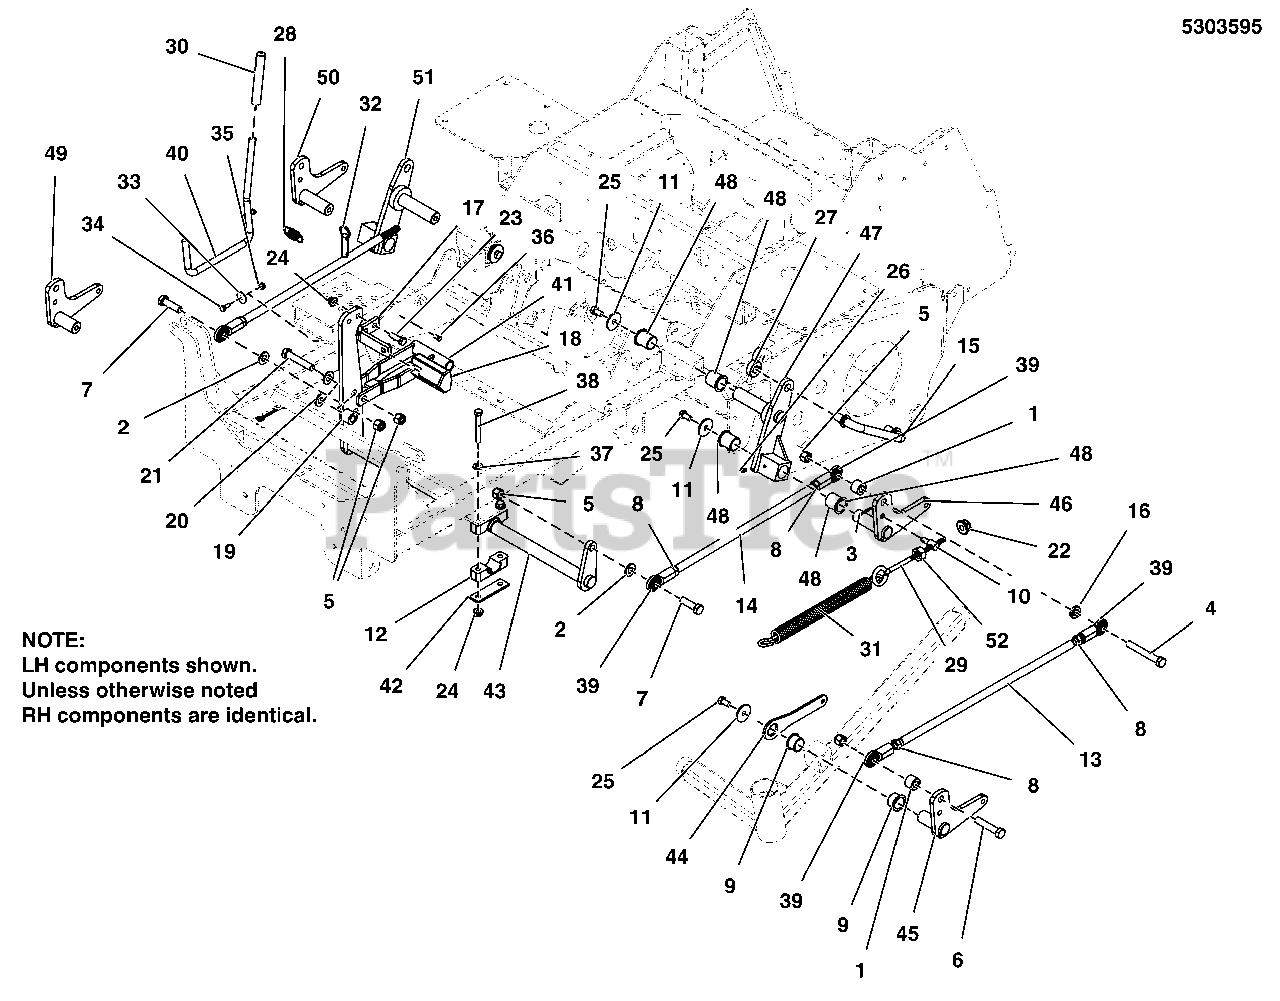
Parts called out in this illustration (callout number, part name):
1	SPACER, .52 X 1.00 X .75, CZ
2	WASHER, 1/2" GR. 9 FLAT
3	PIN, COTTER, 1/8" X 3/4
4	CAPSCREW, Hex Hd, 1/2-13 x 3-1/2
5	NUT, Hex, Nylon Lock, 1/2-13
6	BOLT, 1/2-13 X 2-1/2 GD5 YZ
7	BOLT, 1/2-13 X 1-3/4 GD5 YZ
8	NUT, Hex Jam, 1/2-20
9	BUSHING, 1.00 X 1.13 X .75, PLASTIC
10	ADJUSTER, DECK HANGER
11	WASHER, .390 X 1.50 X .109, YZ
13	ROD, 1/2-20 X 24.50
14	ROD, DECK LIFT, 19.25, CZ
15	ROD, SUSPENSION LINK, IS700, CZ
16	SPACER, .52 X 1.00 X .22, PM, CZ
17	PEDAL, FOOT - BLK
18	RUBBER, FOOT PEDAL
19	SPACER, .52 X 1.00 X .88, PM, CZ
20	WASHER, 1/2
21	BOLT, 1/2-13 X 2-3/4 GD5 YZ
22	NUT, Hex, Nylon Lock, 3/8-16
23	CAPSCREW, Hex Head, 3/8-16 x 1-1/4
24	NUT, 3/8-16, Hex Flange Nylock
25	BOLT, 3/8-16 x 3/4, GD5, YZ WITH PATCH
26	GREASE FITTING, 1/4-28 STRAIGHT
27	COLLAR, 5/8" SPLIT
28	SPRING-EXT, .740 ODX2.025LGX.072WR, BLK
29	EYEBOLT, 3/8-16 X 8, 3 THRD, 1 EYE, CZ
30	GRIP, FOAM, .475 X 4.35 X .095
31	SPRING-EXT, 1.00 ODX13.25LGX.177WR, BLK
32	PIN, HITCH, 1/2 X 2.00 OAL, YP
33	WASHER, 1/4
34	CAPSCREW, Hex Head, 1/4-20 x 5/8, GR5
35	NUT, 1/4-20, GR5 Flanged Nylock, Zinc/Clear
36	PIN, CLEVIS, 1/4 X 1/2, PLATED
37	WASHER, 3/8 (.406 X .816 X .65), Flat, Zinc/Clear
38	CAPSCREW, Hex Head, 3/8-16 X 2-3/4
39	JOINT-BALL .500-20 THD .500ID, CLR ZINC
40	WELD, ROD DECK LIFT, IS700 - BLK
41	WELD, DECK HEIGHT LINK, IS700 - BLACK
42	PLATE, PIVOT BLOCK SUPPORT - BLK
43	WELD, DECK LIFT SHAFT - ORG
44	MOUNT, SPRING, DECK LIFT - ORG
45	WELD, PIVOT DECK LIFT - LH - ORANGE
46	WELD, DECK LIFT LEVER, LH - BLK
47	WELD, REAR LIFT - LH - BLK
48	BUSHING, 1.00 X 1.13 X 1.38, PLASTIC
49	WELD, DECK LIFT LEVER, RH - ORG
50	WELD, DECK LIFT LEVER, RH - BLK
51	WELD, REAR LIFT - RH - BLK
52	NUT, 3/8-16 HEX
